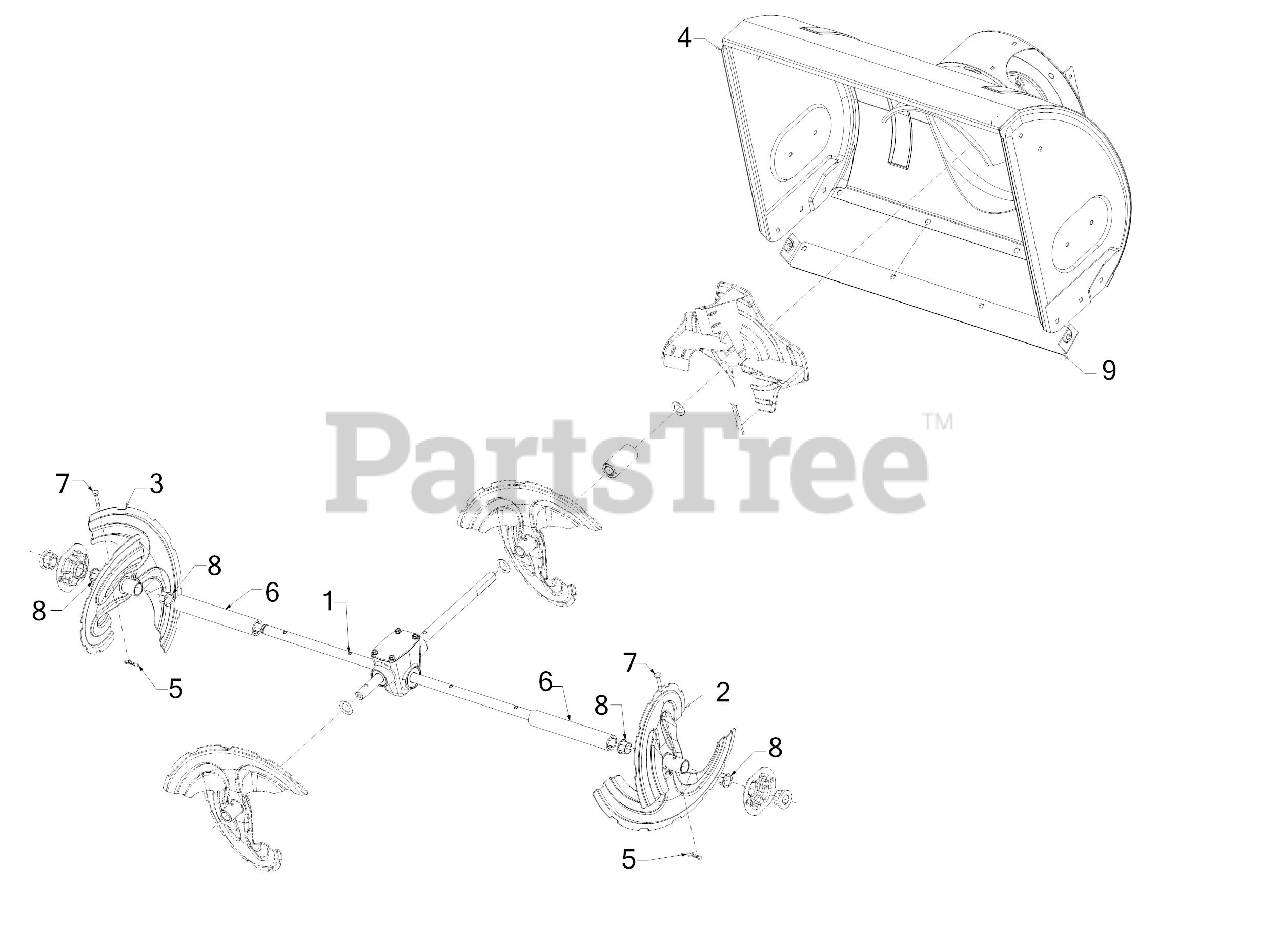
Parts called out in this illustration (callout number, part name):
1	28" AUGER GEARBOX ASSEMBLY
2	AUGER ASSEMBLY (LH)
3	AUGER ASSEMBLY (RH)
4	28" AUGER HOUSING ASSEMBLY
5	BOW TIE COTTER PIN 1/4-5/16
6	SPACER
7	SHEAR PIN .25 x 1.50 GR2
8	FLANGE BUSHING
9	28" SHAVE PLATE
